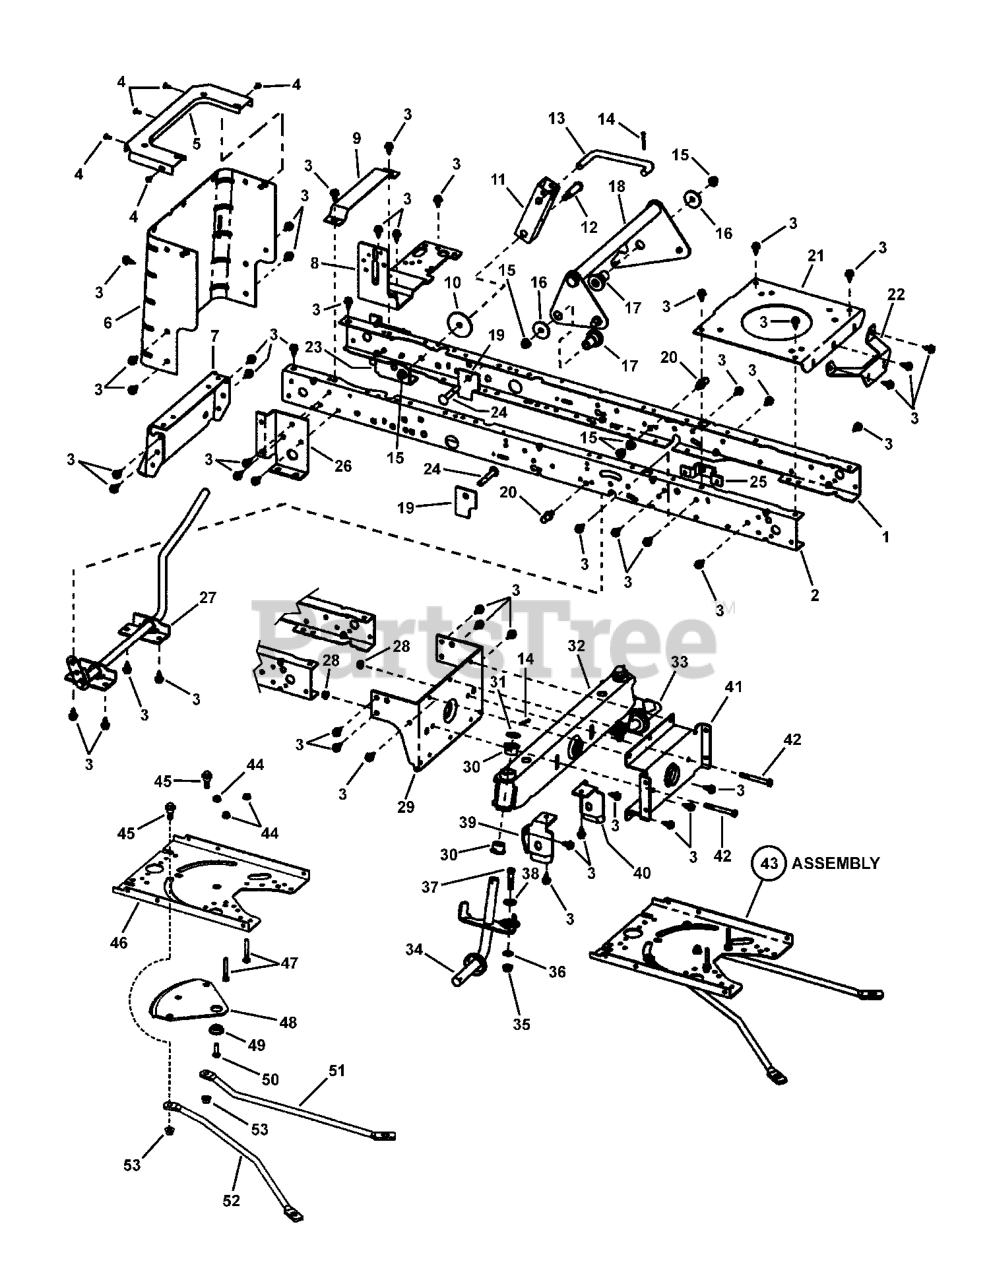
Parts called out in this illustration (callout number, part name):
1	RAIL - FRAME LH
2	RAIL FRAME RH
3	CAPSCREW 5/16-18
4	SCREW, 10-24X.50 SELF-TAP SEMS
5	TOP - REAR PLATE
6	PLATE REAR
7	PLATE - HITCH
8	BRACKET SHIFT RH
9	BRKT - BATTERY SUPPORT
10	HER PLAIN .406 X 2.25
11	BRACKET - PIVOT
12	SHOULDER BOLT, 1.563L X 0.75D X 9/16 X 3/8-16
13	LINK - LIFT HANDLE
14	PIN,COTTER 1/8 X 1.25 YZ
15	HFLN, 3/8-16 YZ
16	HER 1-1/2 OD
17	SPACER - LIFTER PIVOT
18	LIFTER ASSY (WELDMENT)
19	PLATE STIFFENING
20	PIN - THREADED SHOULDER (3/8-16 thread)
21	PLATE - ENGINE
22	BRACKET, MUFFLER MOUNTING
23	BRACKET - TRANSAXLE L.H.
24	RHSSNB,3/8CX2-1/2
25	BRACKET - BELLCRANK
26	BRACKET - TRANSAXLE R.H.
27	ASSEMBLY - BRAKE LEVER (WELDMENT)
28	HFLN, 5/16-24 BZ
29	BRACKET - HANGER REAR
30	BEARING SPINDLE
31	HER,.77X1.13X.06
32	WELDMENT, AXLE SECTION ASSY
33	WELDMENT - SPINDLE LH
34	WELDMENT - SPINDLE RH
35	NUT, HEX FLANGE, 3/8-16 NC
36	FW, .41 X.82 X 16GA
37	BOLT, HEX, 3/8-16 UNC X 1.50 BRIGHT ZINC
38	HER, FLAT, 25/64" ID X 1" OD X 14 GA.
39	HANGER DECK RH
40	HANGER DECK LH
41	HANGER - AXLE
42	HHB, 5/16-24 X 2.75 BOLT
43	SECTOR GEAR ASSY (GEAR DRIVE - LT)
44	HFLN, 5/16-18 BZ
45	BOLT, SHOULDER 3/8-16
46	PLATE, STEERING MOUNT
47	SCREW - GUIDE
48	GEAR - SECTOR
49	BEARING - SECTOR GEAR
50	HHCS, 5/16-18 X 1 YZ
51	DRAG - LINK LH
52	DRAG - LINK RH
53	HFLN, 3/8-16 YZ
